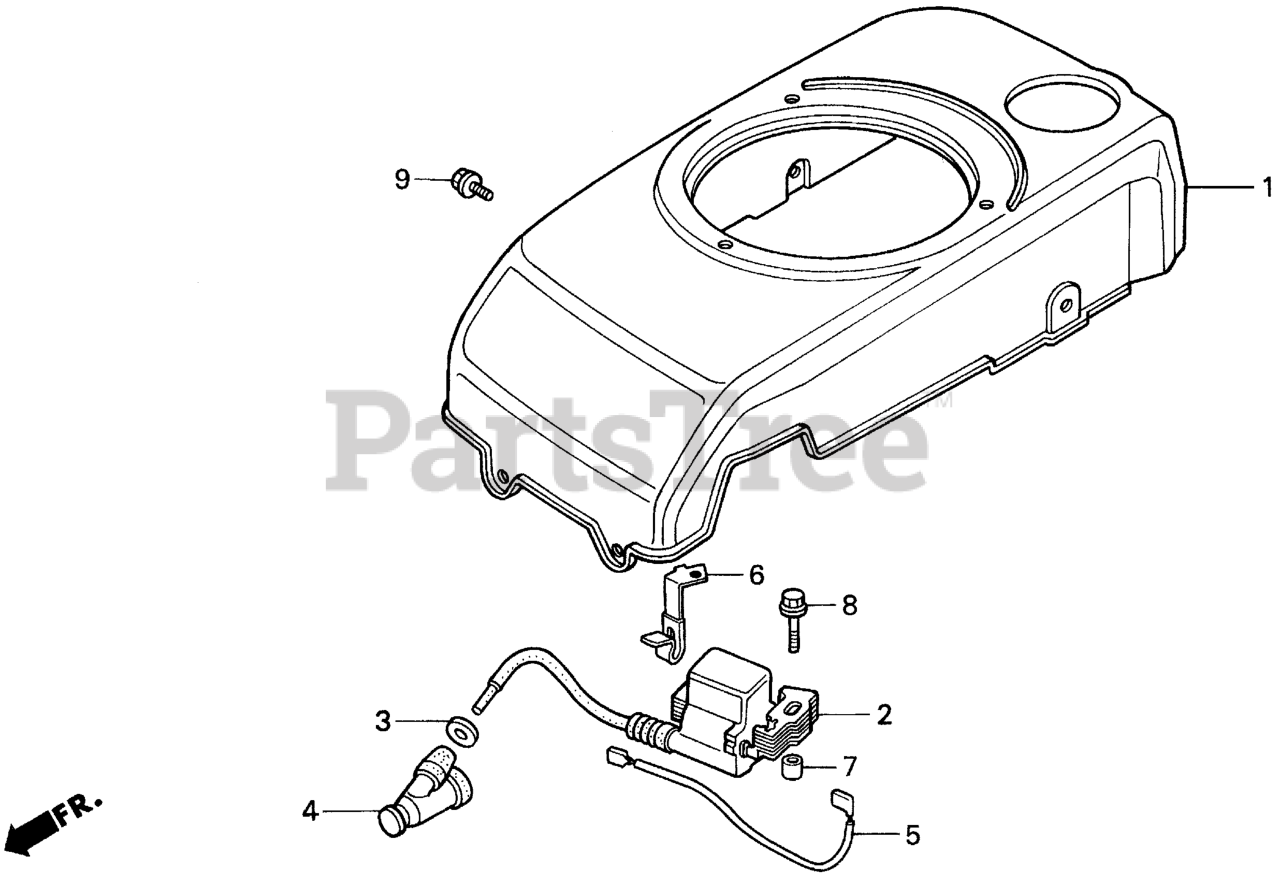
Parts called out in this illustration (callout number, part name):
1	COVER, FAN *R8* (BRIGHT RED)
2	COIL ASSY., IGNITION
3	GROMMET, IGNITION WIRE
4	TERMINAL ASSY., IGNITION
5	WIRE, ENGINE STOP
6	CLAMP, WIRE
7	COLLAR, ROTO-STOP
8	BOLT, FLANGE (6X35)
